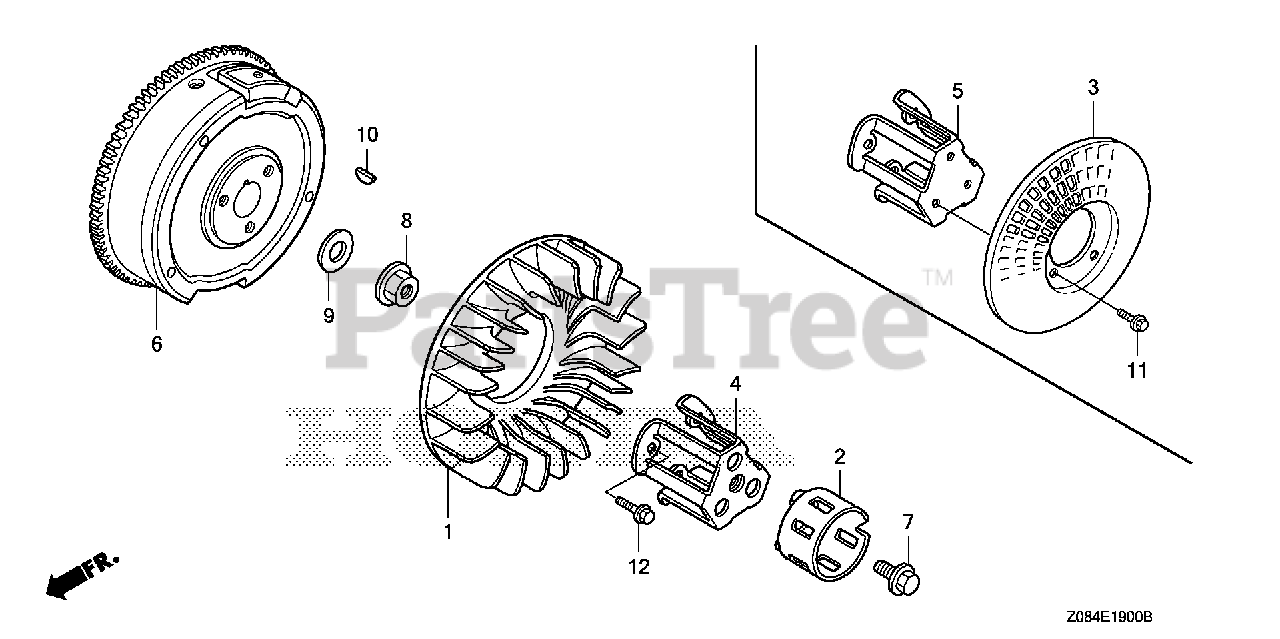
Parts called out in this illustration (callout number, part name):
1	FAN, COOLING
2	PULLEY, STARTER
3	GRID, SCREEN (P.T.O.)
4	SPACER, STARTER PULLEY MOUNTING
5	HOLDER, SCREEN GRID
7	BOLT, UBS (12X28)
8	NUT, FLANGE (20MM)
9	WASHER (20MM)
10	KEY, SPECIAL WOODRUFF (25X18)
11	BOLT, FLANGE (6X12)
12	BOLT, FLANGE (8X16)
